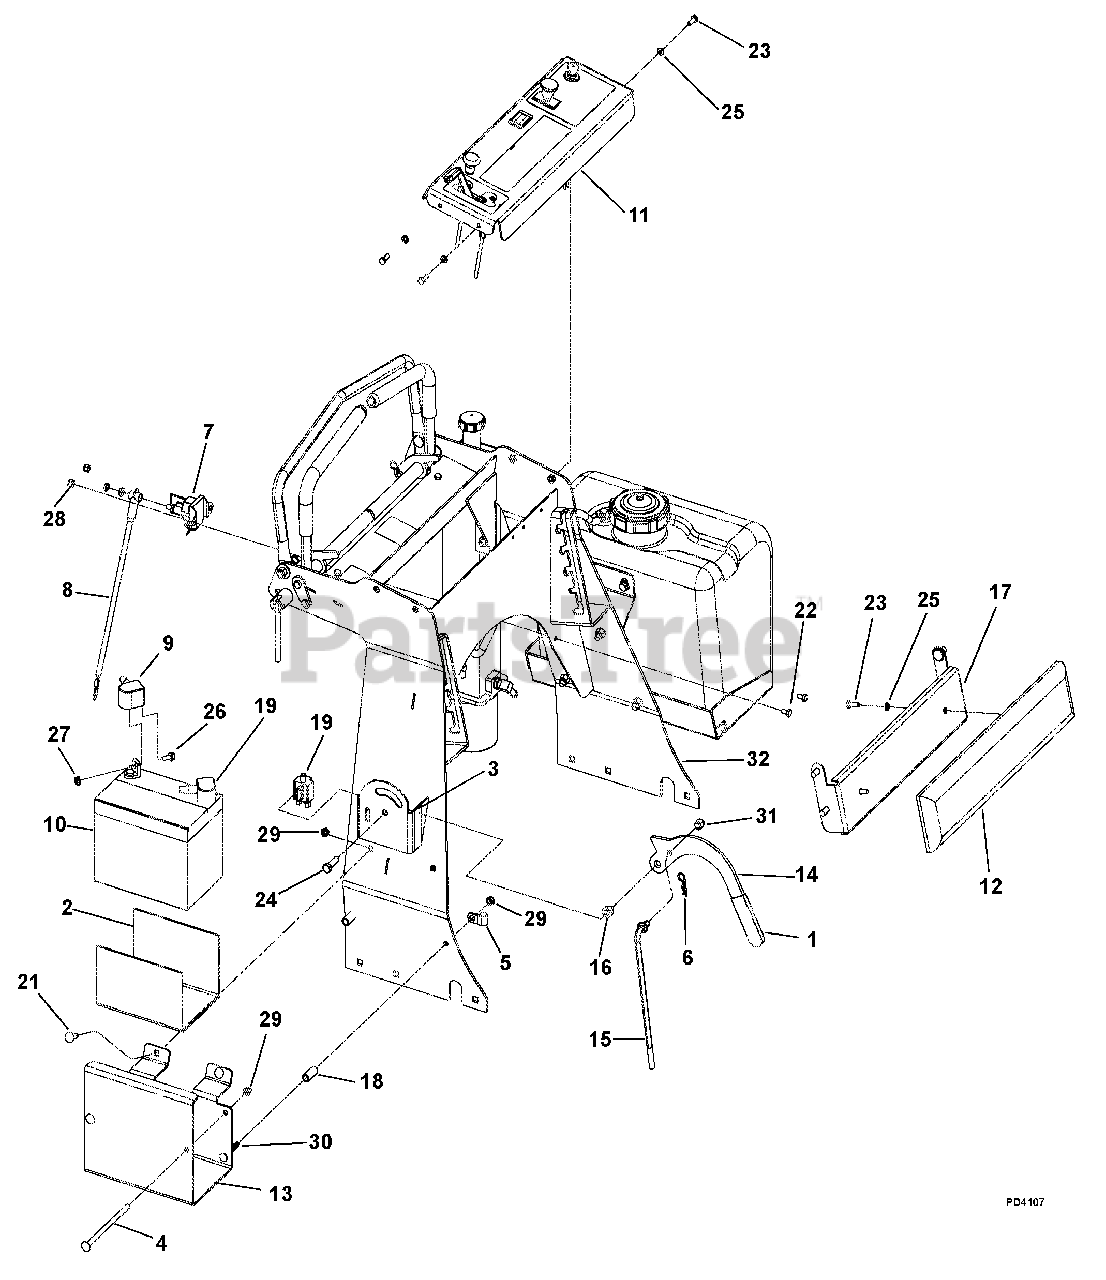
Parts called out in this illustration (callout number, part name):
1	Grip
2	Isolator Pad, Battery
3	Decal, Park Brake
4	Cap Screw, 5/16" x 6"
5	P-Clip,.500 Insulated
6	Pin, Hair Internal .09 x 1.65
7	Solenoid
8	Starter Cable
9	Cable, Battery Starter 48"
10	Battery
11	Assembly, Control Panel
12	Pad, Thigh
13	Tray, Battery
14	Lever, Brake
15	Link, Brake
16	Bushing, Brake Pivot
17	Weldment, Thigh Pad Bracket
18	Bushing, .364 x .540 x 1.250
19	Switch, NO-NO-NC Grey Plunger
20	Cable, Battery Starter 48"
21	Bolt, Round Head Square Neck .38 x 1.00
22	Bolt, Hex .25-20 x .50 Grade 5
23	Bolt, Hex .25-20 x .75 Grade 5
24	Bolt, Hex .38-16 x 1.25 Grade 5
25	Washer, Locking .25 x .062 Regular
26	Bolt, 1/4-20 x .625 WSH
27	Nut, Locking, Flange .250-20
28	Nut, Locking, Nylon .250-20
29	Nut, Locking, Nylon .312-18
30	Bolt, Round Head Square Neck Full Thread .31-18 x 2.0 Grade 5
31	Nut, Lock, Nylon .38-16
32	Weldment, Console with Decals S/O
